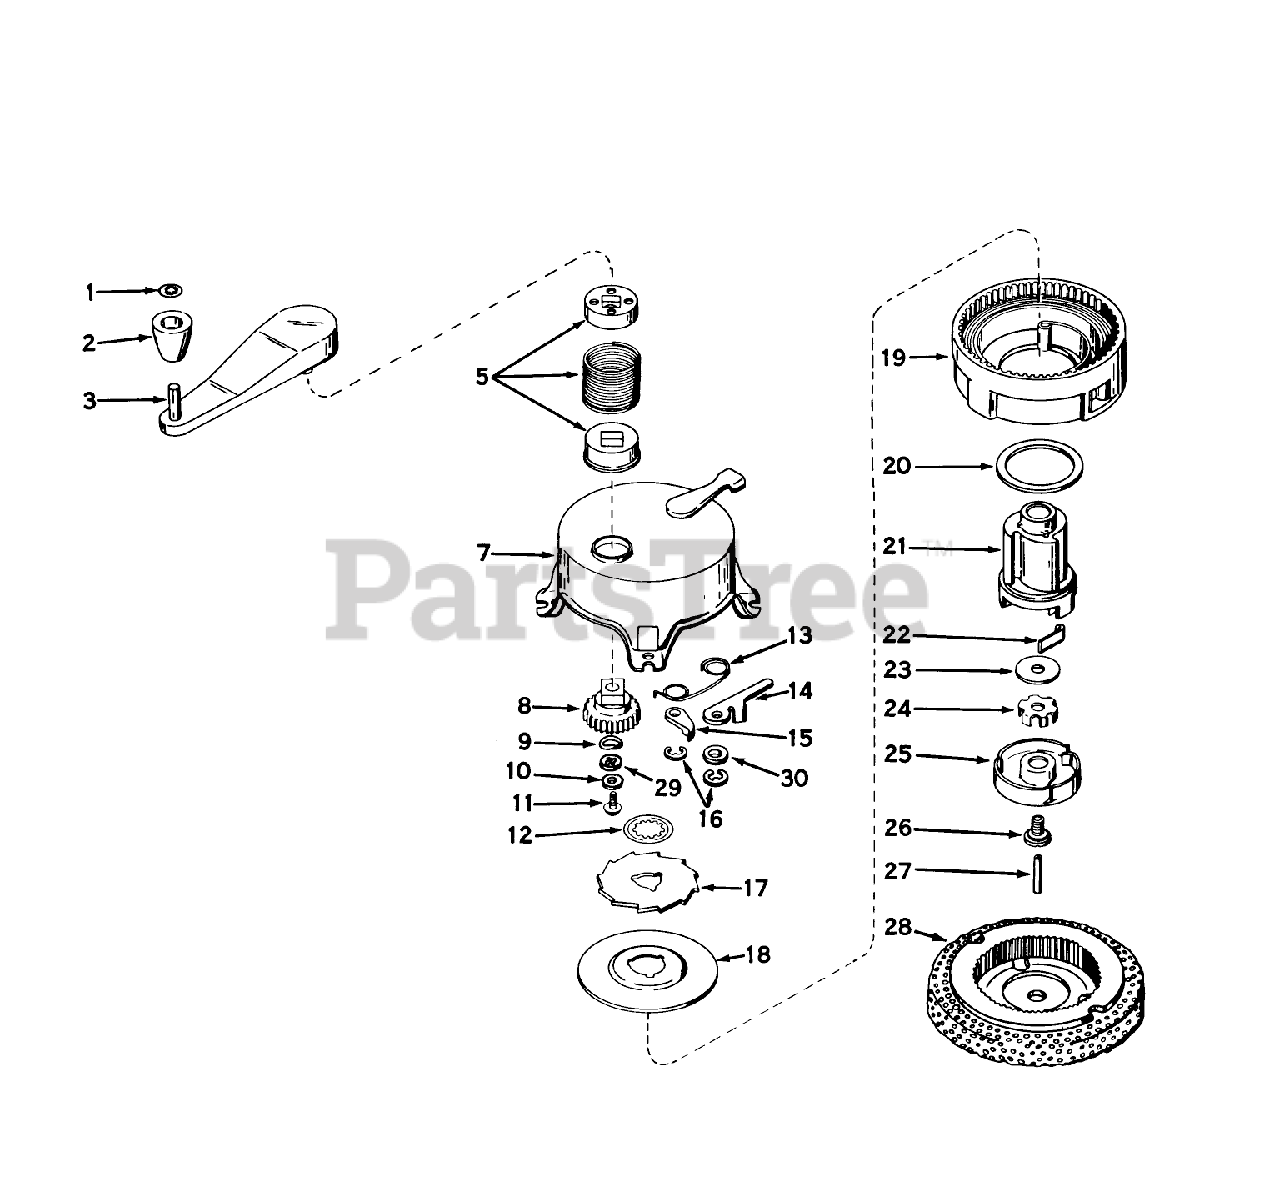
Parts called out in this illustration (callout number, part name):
1	Fastener, Handle
2	Knob, Starter handle
3	Handle Assy.
5	Clutch Assy.
7	Housing Assy.
8	Gear, Wind
9	Washer, Wave
10	Washer, Brake
11	Screw
12	Ring, Retaining
13	Spring, Release dog
14	Dog, Release
15	Dog, Lock
16	Retainer, Dog pivot
17	Gear Release
18	Cover, Spring
19	Spring and Keeper Assy.
20	Washer, Hub
21	Hub, Starter
22	Dog-Starter
23	Washer, Brake
24	Brake
25	Retainer
26	Screw, Brake (Left Hand Thread)
27	Pin, Centering
28	Hub Screen
29	Washer
30	Ballast Box w/Brackets Braces
